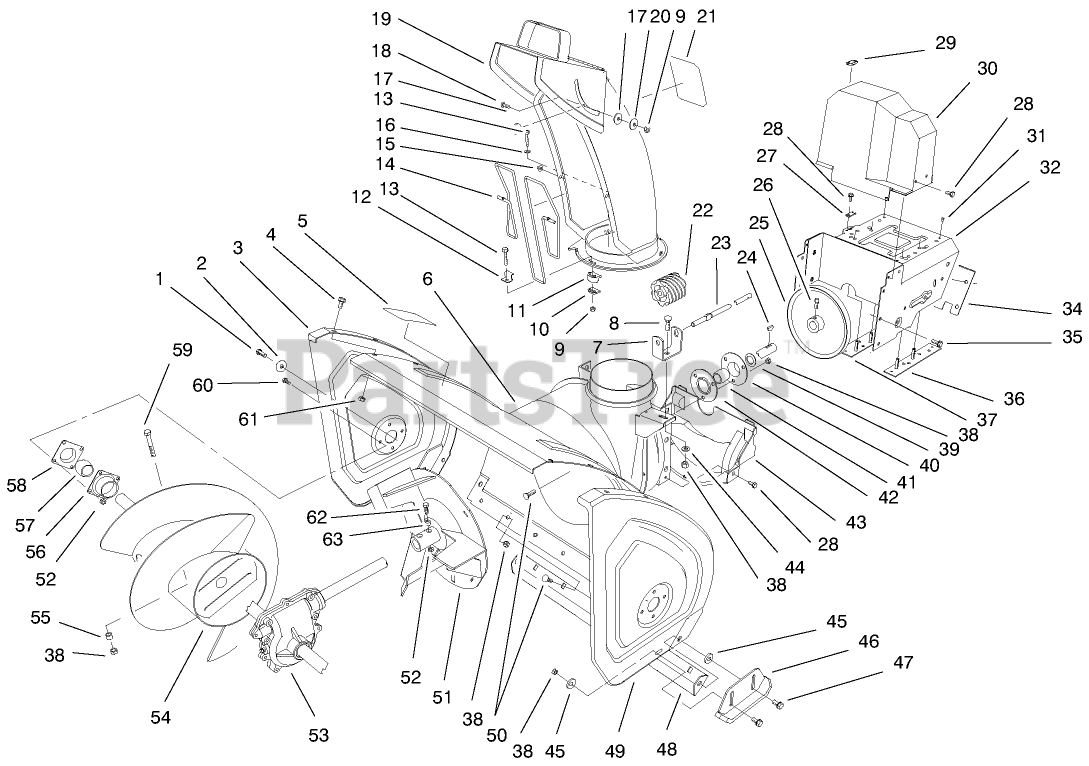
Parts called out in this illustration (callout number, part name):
1	SCREW-HH
2	WASHER
3	PLATE-SIDE, RH
4	SCREW-HHF
5	DECAL-WARNING, AUGER
7	BRACKET-WORM, CHUTE
8	BOLT-CARR
9	NUT-LOCK, NI
10	PLATE-RETAINER, CHUTE
11	RETAINER-CHUTE
12	CLIP-GUARD, CHUTE
13	SCREW-HSH
14	GUARD-CHUTE
15	NUT-PUSH
16	WASHER-FLAT
17	WASHER-PLASTIC
20	WASHER-FLAT
21	DECAL-DANGER
21	DECAL - DANGER
22	GEAR-WORM
23	ROD-CHUTE, LOWER
24	KEY-WOODRUFF
26	SCREW-SET, SQH
27	RETAINER-CABLE
28	SCREW-HWH
29	COVER-CABLE
30	COVER-BELT, UPPER
31	RIVET-POP
34	COVER-FRAME, ENGINE
35	SCREW-HWHTF
36	LH FRAME PLATE ASM
37	RH FRAME PLATE ASM
38	NUT-LOCK, NI
39	WASHER-THRUST
40	FLANGE-CUP, BEARING
41	BEARING-BALL
42	FLANGE-CUP, BEARING
43	COVER-BELT, LOWER
44	WASHER-PLAIN
45	WASHER
46	SKID ASM
47	SCREW-HHF
48	BLADE-SCRAPER, 28"
49	PLATE-SIDE, LH
50	SCREW-CARR
51	IMPELLER ASM-4 BLADE
52	NUT-LOCK, NI
53	28IN AUGER GEARCASE ASM
54	AUGER ASM-RH, 28"
55	SPACER-HUB, AUGER
56	BEARING-FLANGE, FRONT
57	BEARING
58	BEARING-FLANGE, REAR
59	SCREW-HH
60	SCREW-HH
61	NUT-LOCK, NI
62	SCREW-HHF
63	SPACER
